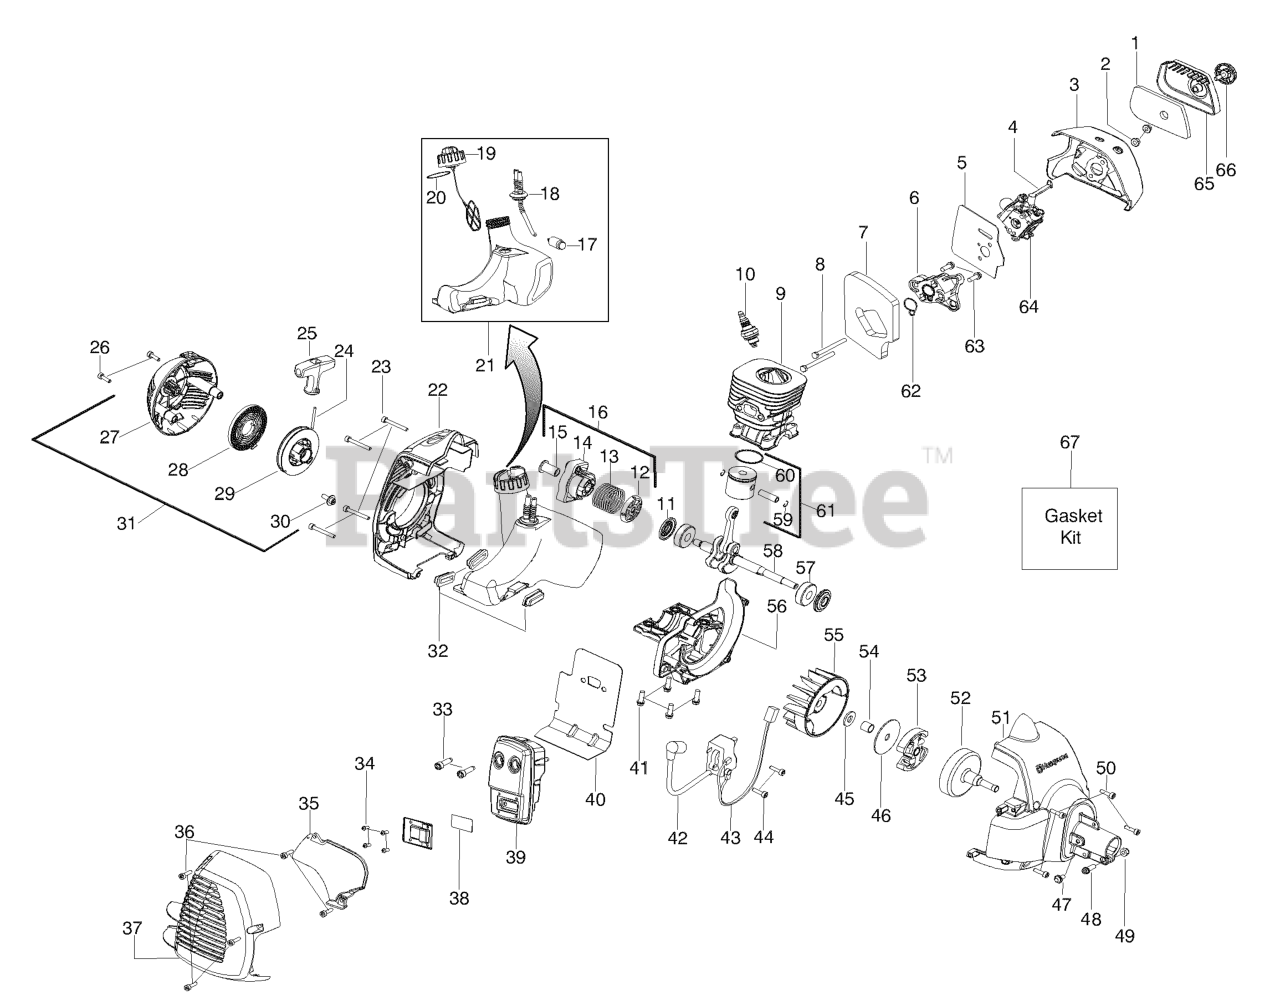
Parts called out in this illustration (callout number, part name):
1	FILTER AIRBOX
3	Air Box
4	CHOKE LEVER
5	KIT GASKET CARB
6	CARB ADAPTOR
7	KIT GASKET 28CC TRIMMER
8	BOLT CARB ADAPTOR
9	CYLINDER
10	Plug-Spark
11	KIT SEAL CRANKSHAFT
12	Washer - Starter
13	Spring - Starter Cup
14	Assy - Starter Cup
15	Coupling - Starter
16	COUPLING-STARTER
17	FUEL PICK-UP ASSY
18	KIT FUEL LINE
19	ASSY-CAP W/RETAINER
20	O RING NITRILE
21	FUEL TANK ASSY
22	REAR SHROUD
25	STARTER HANDLE GRAY
26	SCREW M5-0.8X30MM
27	STARTER HOUSING
28	%KIT STARTER SPRING
29	KIT STARTER PULLEY
31	ASSY-STARTER HSG.
32	ISOLATOR FUEL TANK
33	BOLT MUFFLER
34	SCREW-10-16 X 1/2 HI-LO
35	SHIELD HEAT
36	SCREW M4 X 1.75 PT 16MM
37	GUARD-MUFFLER
38	KIT SPARK ARRESTOR SCREEN
39	ASSY-MUFFLER
40	GASKET PAPER METAL
41	SCREW-M5-0.8 X 25MM(TAP)
42	IGNITION MODULE MB45
43	ASSY MODULE LEAD WIRE
44	SCREW M4 X .70 TT 16MM
45	WASHER CLUTCH
46	WASHER-CLUTCH
49	LOCKNUT-HEX 10-24
50	SCREW M4 X .70 TT 16MM
51	FAN HSG ASSY
52	Assy-Clutch Drum
53	%KIT CLUTCH ASSY
54	SPACER FLYWHEEL
56	CRANKCASE CASTING
57	BEARING RADIAL BALL (6201)
58	KIT CRANKSHAFT ASSY
59	WRIST PIN RET.
60	RING PISTON
61	KIT PISTON 28CC TRIMMER
62	KIT GASKET 28CC TRIMMER
63	SCREW-M5-0.8 X 25MM(TAP)
64	Kit-Carb.
65	COVER-AIR BOX
66	KNOB ASSY AIRBOX COVER
67	KIT GASKET 28CC TRIMMER
